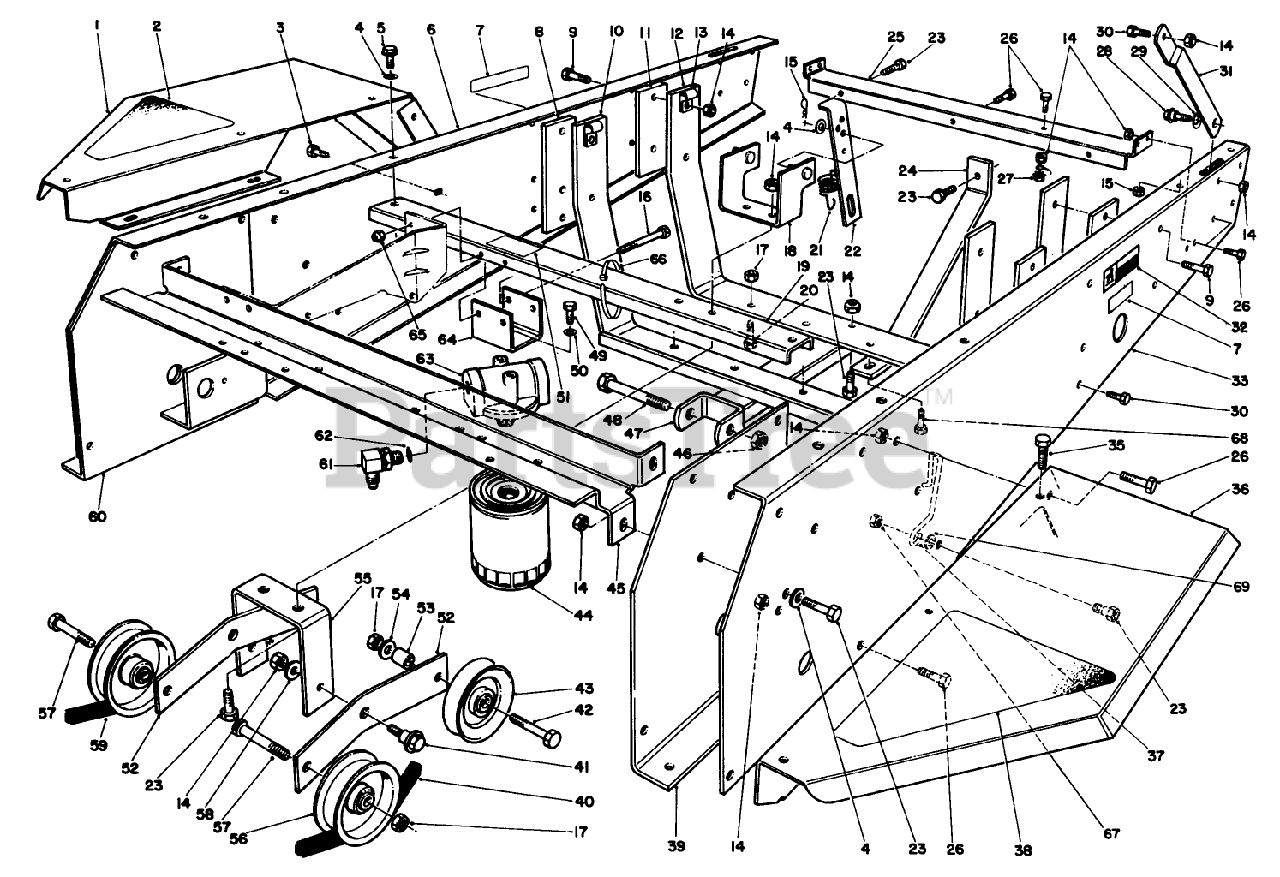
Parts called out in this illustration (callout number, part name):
1	Fender R.H
2	RH FENDER PAD
3	SCREW-HHF
4	WASHER-PLAIN
5	SCREW-HWHTF
6	Channel-Side R.H.
7	DECAL-WARNING
8	FRONT ENG PLATE
9	SCREW-HH
10	ENGINE MT WA B
11	REAR ENG PLATE
12	ENGINE MOUNT B
14	NUT-LOCK, NI
15	PIN-COTTER
16	SCREW-HH
17	NUT-LOCK, NI
18	Anchor-Spring
19	MIDDLE CHANNEL WA B
20	SCREW-HH
21	IDLER SPRING
22	IDLER ANCHOR LINK
23	SCREW-HH
24	TENSION BAR B
25	Support-Shield
26	SCREW-HH
27	NUT-KEPS
28	SCREW-SHOULDER
29	WASHER-SPRING
30	SCREW-HH
31	Stop-Hood Lower
32	DECAL-HOT
33	Channel-Side LH.
35	SCREW-HHFTF
36	Fender L.H.
37	BELT GUIDE
38	LH FENDER PAD
39	Axle Stand-LH.
40	V-BELT, JACKSHAFT
41	SCREW-SHOULDER
42	SCREW-HH
43	PULLEY
44	FILTER-OIL, TRANSMISSION
45	Channel-Front
46	NUT-LOCK
47	CYL MOUNT WA B
48	SCREW-HH
49	SCREW-HH
50	WASHER-LOCK
51	DECAL-OIL
52	IDLER LEVER
53	SPACER-WEIGHT
54	WASHER-FLAT
55	IDLER MT BRKT
56	PULLEY
57	SCREW-HH
58	WASHER
59	V-BELT, TRACTION
60	Axle Stand R.H.
61	FITTING-ELBOW, 90
62	O-RING
63	FILTER HD ASM
64	BRACKET - FILTER HEAD
65	NUT-LOCK, NI
66	TIE-CABLE
67	NUT-HF
68	SCREW-HWHTF
69	WASHER-LOCK
